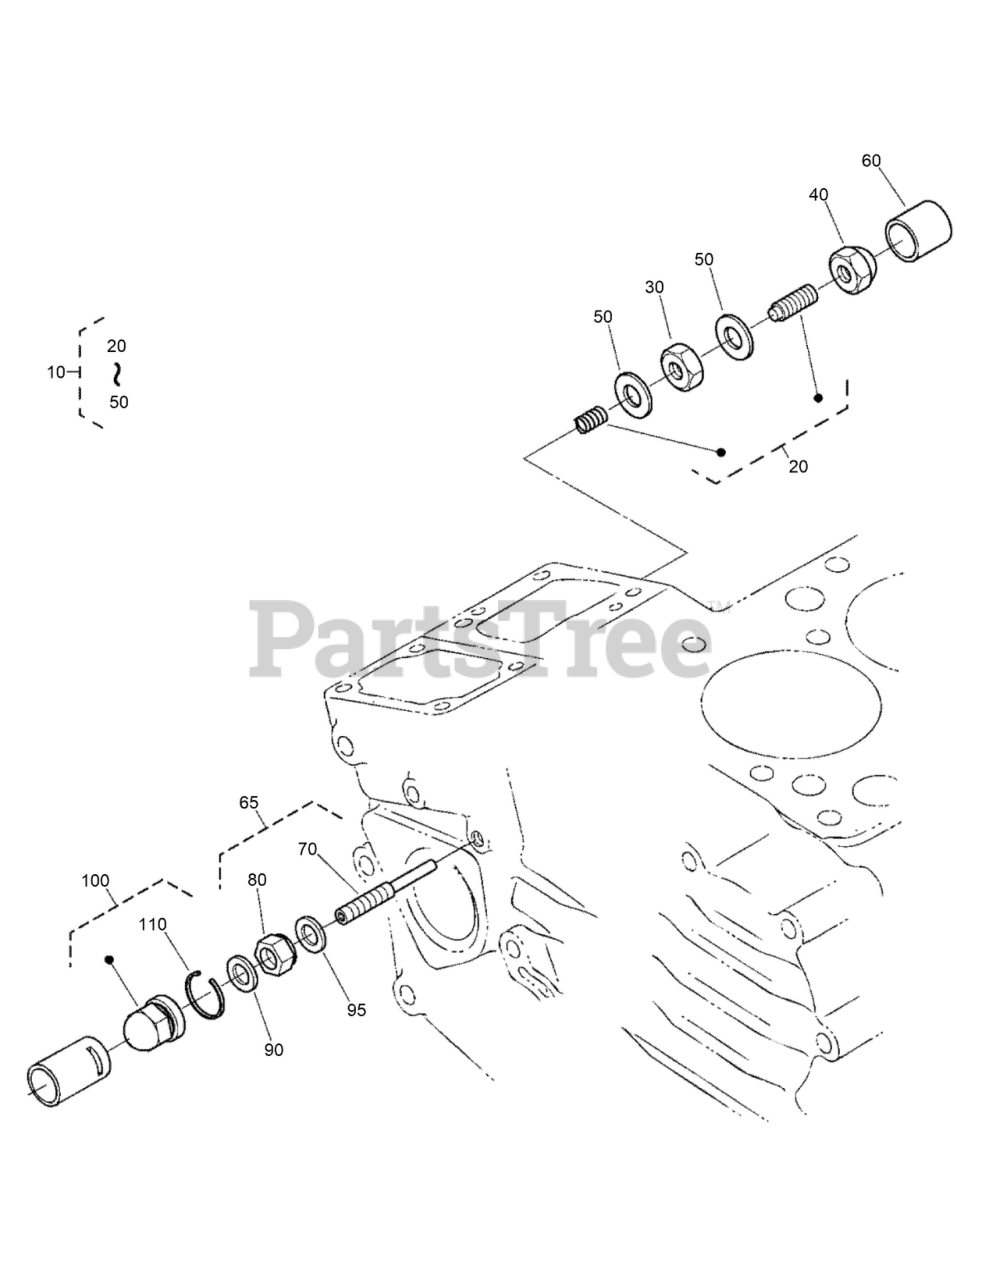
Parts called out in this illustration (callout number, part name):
10	IDLE APPARATUS ASM
20	ADJUSTING BOLT ASM
40	NUT-CAP
50	GASKET
65	BOLT,ASSY(ADJUSTING)
70	BOLT-ADJUSTING
80	NUT-LOCK
90	GASKET
95	GASKET
100	NUT,CAP,ASSY
110	CIRCLIP-INT
